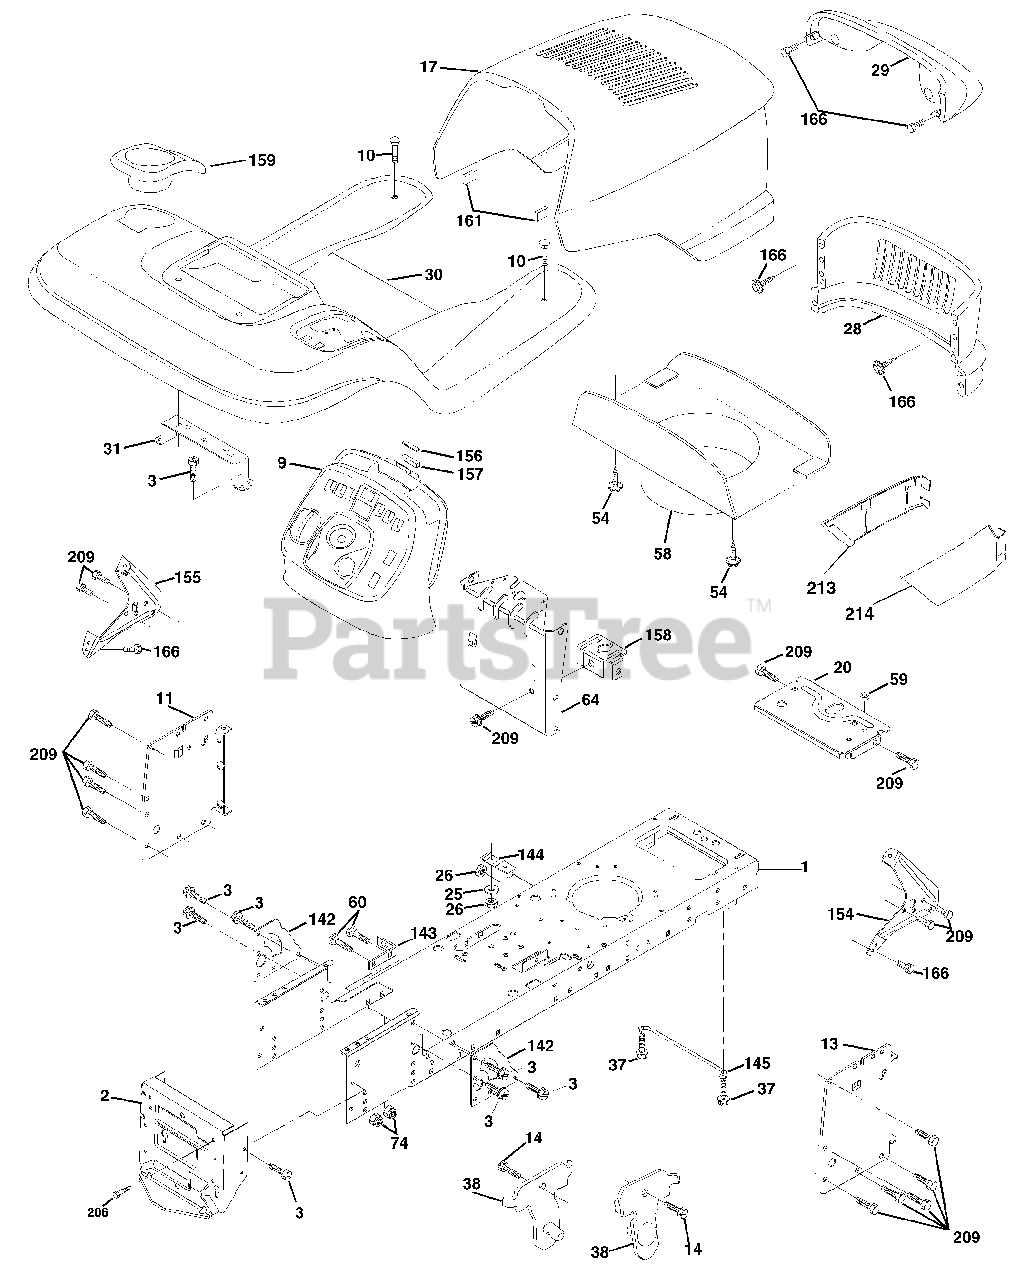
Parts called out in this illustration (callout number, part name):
1	Chassis
2	Drawbar
3	Screw 3/8-16x3/4
9	Dash
10	Bolt 3/8-16 x 1
11	Panel Dash Lh
13	Panel Dash Rh
14	Screw Thdrol 3/8-16 x 1/2
17	Hood
20	Plate Battery
25	Washer 13/32 X 13/16 X 12 Ga
26	Nut Lock Hex W/Ins 3/8-16 Unc
28	Grille
29	Light Box Asm W/Lens
31	Bracket Fender
37	Screw Thdrol 6/16-18 x 1/2 TYT
38	Bracket, Asm. Pivot Mower Rear
54	Screw Hex Wshd 8-18 x 7/8
58	Duct Hood
59	Bushing Snap
60	Bolt Rd Hd Sqnk 3/8-16 Unc x 3/4
64	Dash Lower
74	Nut Crownlock 3/8-16 Unc
142	Plate Reinforcement STLT
143	Bracket Swaybar Chassis
144	Bracket Footrest
145	Rod Pivot Chassis/Hood
154	Bracket Dash Rh
155	Bracket Dash Lh
156	Striker Plate
157	Magnet Stealth
158	Bracket Parking Brake
159	Cupholder
161	Extrusion Bumper
166	Screw Hw Hd Hi-Lo #13-16 x 3/4
206	Bolt Shoulder 5/16-18
209	Screw Hexwsh Thdrol 3/8-16 x 3/4
213	Skirt Grille Lh
214	Skirt Grille Rh
